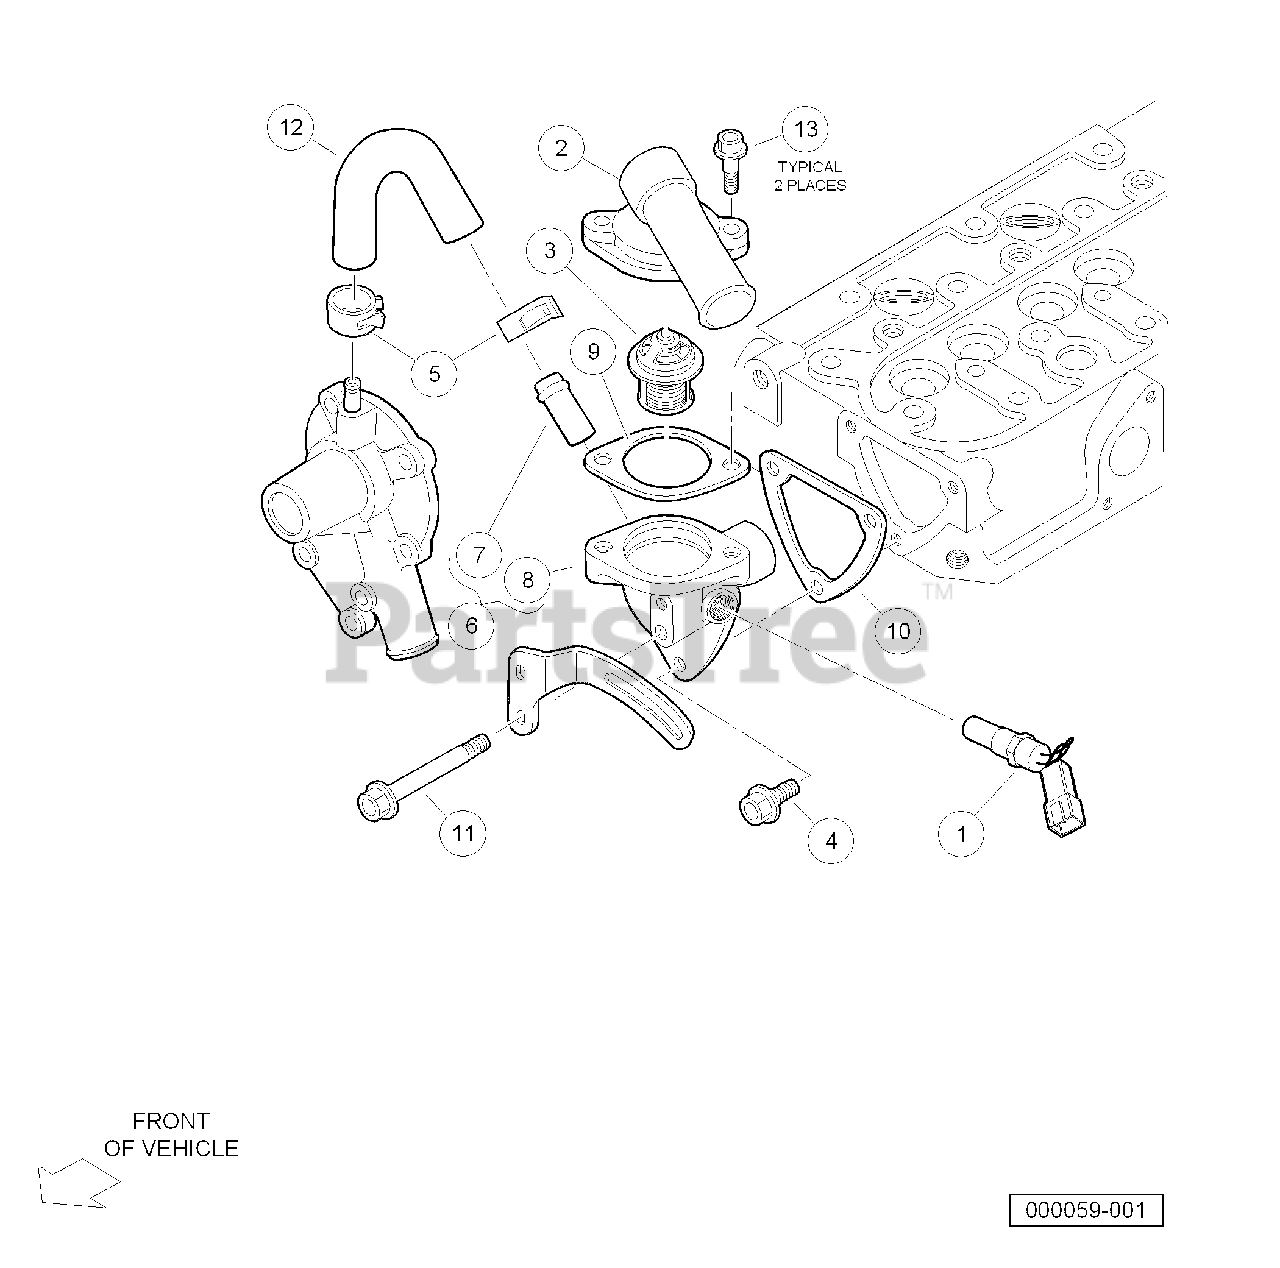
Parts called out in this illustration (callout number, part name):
1	Sensor, Coolant Temp
2	Cover, Thermostat
3	Assy, Thermostat
4	Bolt, M6 X 1 X 20
5	Band, Pipe
6	Flange, Water
7	Pipe, Water Return, D722
8	Flange, Water
9	Gasket, Thermostat
10	Gasket, Water Flange
11	Bolt, Alt, D722, Stay Lower
12	Pipe, Water Return, D722
13	Bolt, D722, Thermostat Cover
